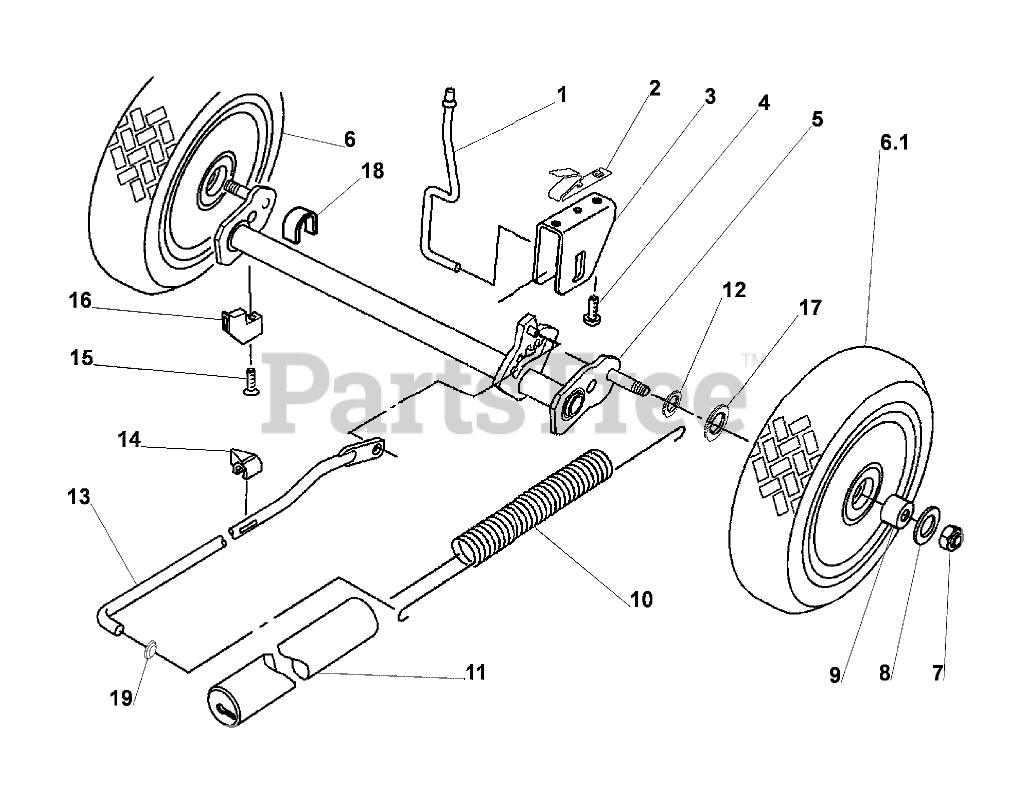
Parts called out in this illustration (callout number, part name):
1	ROD-TRIGGER
2	SPRING-RETURN, TRIGGER
3	SADDLE-HEIGHT OF CUT
4	SCREW-RH
5	AXLE-REAR
6	Wheel-Rear (incl. Ref.# 9)
6.1	Smartwheel-Rear (incl. Ref.#9)
7	NUT-HH
8	WASHER-WHEEL
9	BUSHING
10	SPRING-COUNTERBALANCE
11	COVER-SPRING
12	CAP-AXLE, REAR
13	ROD-LINK
14	INDICATOR-HEIGHT OF CUT
15	SCREW-RETAINER
16	DECAL-ENGAGEMENT
17	WASHER-WAVE
18	CAP-AXLE, REAR
19	NUT-PUSH
